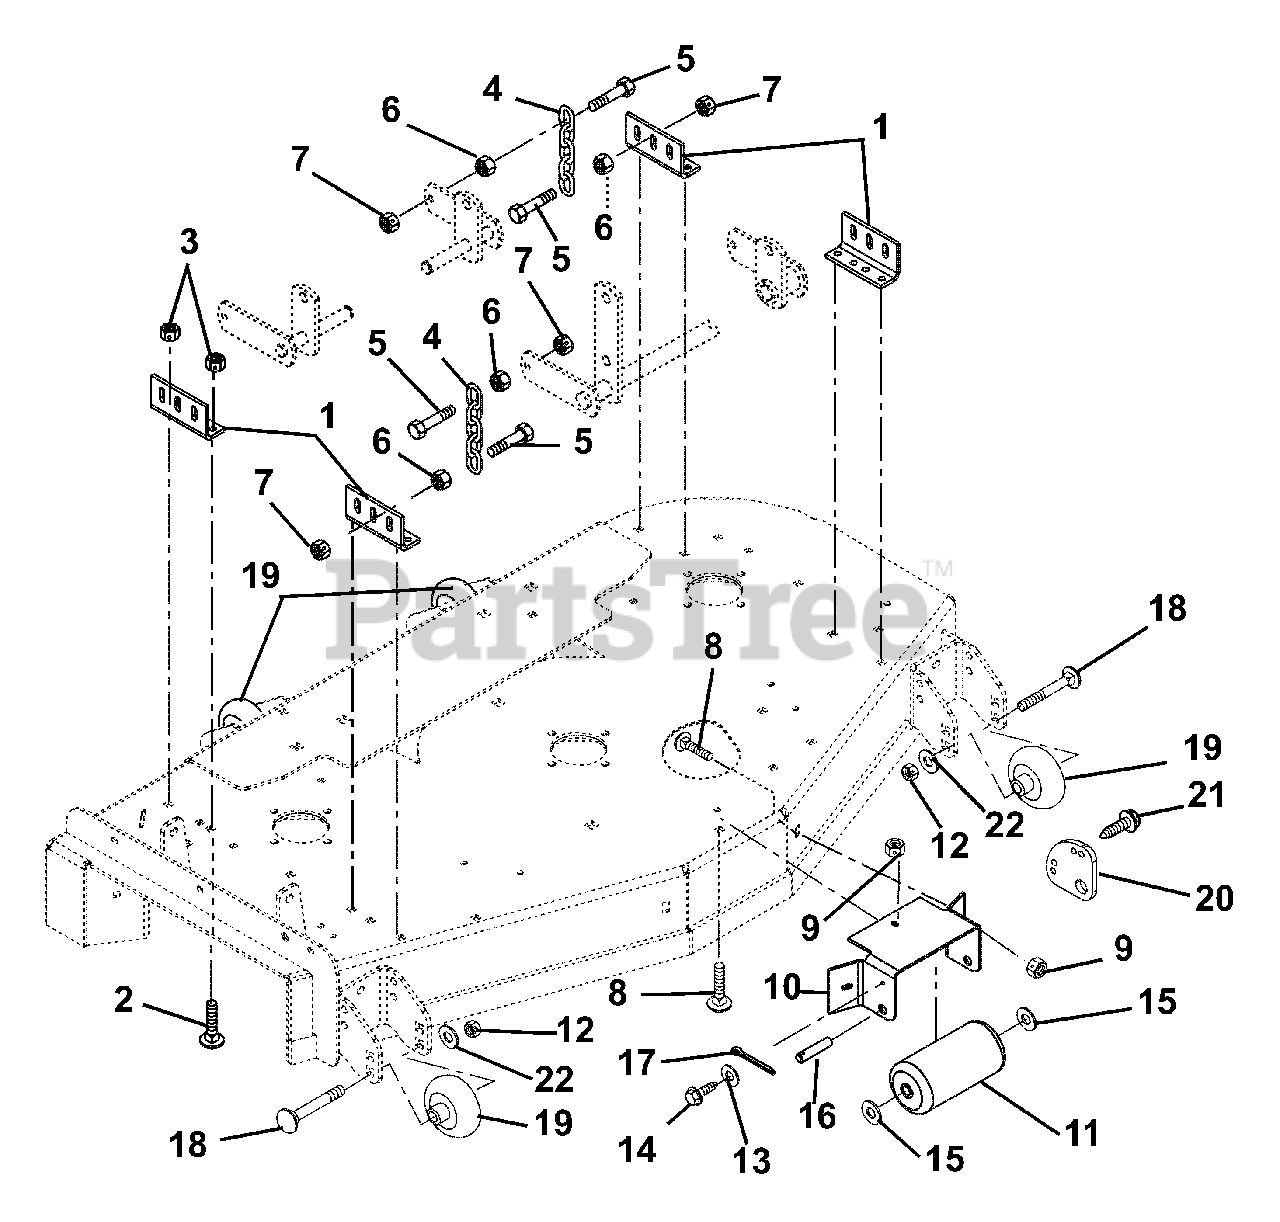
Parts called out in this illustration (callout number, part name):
1	MOWER MOUNTING BRACKET - RED
2	@BLT-RDHDSQNK .38-16X1.00 G5YZ
3	@NUT-LK-TOP-FLG .38-16 YWZC
4	CHAIN, LINK
5	BLT-HEX M12X1.75X55 GR5 YZ
6	NUT-SPNLK-FLG M12-1.75 YZ
7	NUT-LK-TOP-FLG M12-1.75 YZ
8	@BLT-RDHDSQNK .38-16X1.00 G5YZ
9	@NUT-LK-TOP-FLG .38-16 YWZC
10	BRACKET - ANTI-SCALP ROLLER
12	@NUT-LK-NYL .50-13 YWZC
13	@WSHR-FL-STL.281X.62X.065 YWZC
14	SCR-TAP .25-20X.75 HWH TR YWZ
15	@WSHR-FL-STL.656X1.31X.095 YWZ
17	@PIN-CTR .25X2.00 YWZC
18	BLT-RDHDSQNK .50-13X5.00 GR5YZ
19	WHEEL, 3X5
20	ANTI-SCALP WASHER - RED
21	SCR-TAP.250-20X.62 HWH BLK ZC
22	@WSHR-FL-STL.531X1.06X.095YWZC
